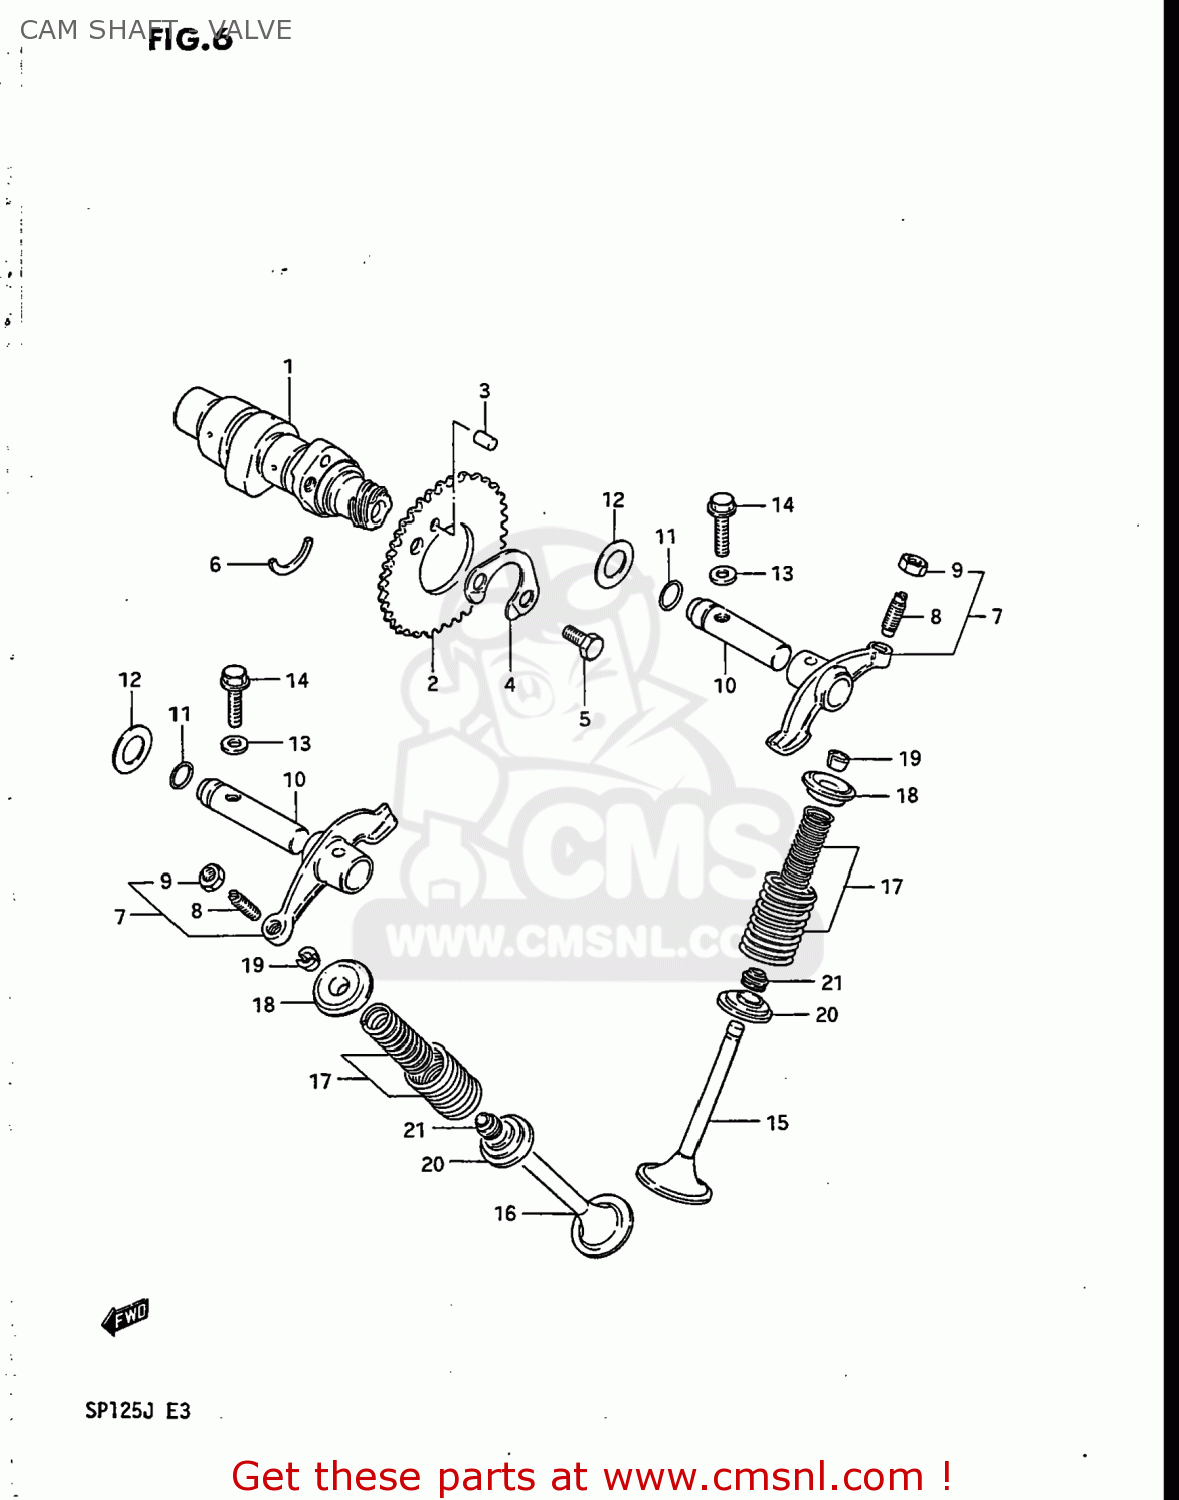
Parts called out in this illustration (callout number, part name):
1	CAMSHAFT
2	SPROCKET,CAMSHAFT
3	PIN(5X8)
4	WASHER,SPROCKET
5	BOLT(6X10.5)
6	C RING
7	ARM,VALVE ROCKER
8	SCREW,TAPPET ADJUSTING
9	NUT,ADJUSTING SCREW
10	SHAFT,VALVE ROCKET
11	O RING(D:1.9,ID:8.6)
12	WASHER
13	GASKET(5.8X13X1.2) (NAS)
14	BOLT
15	VALVE,INTAKE
16	VALVE,EXHAUST
17	SPRING SET,VALVE
18	RETAINER,VALVE SPRING
19	COTTER,VALVE
20	SEAT,VALVE SPRING
21	OIL SEAL
